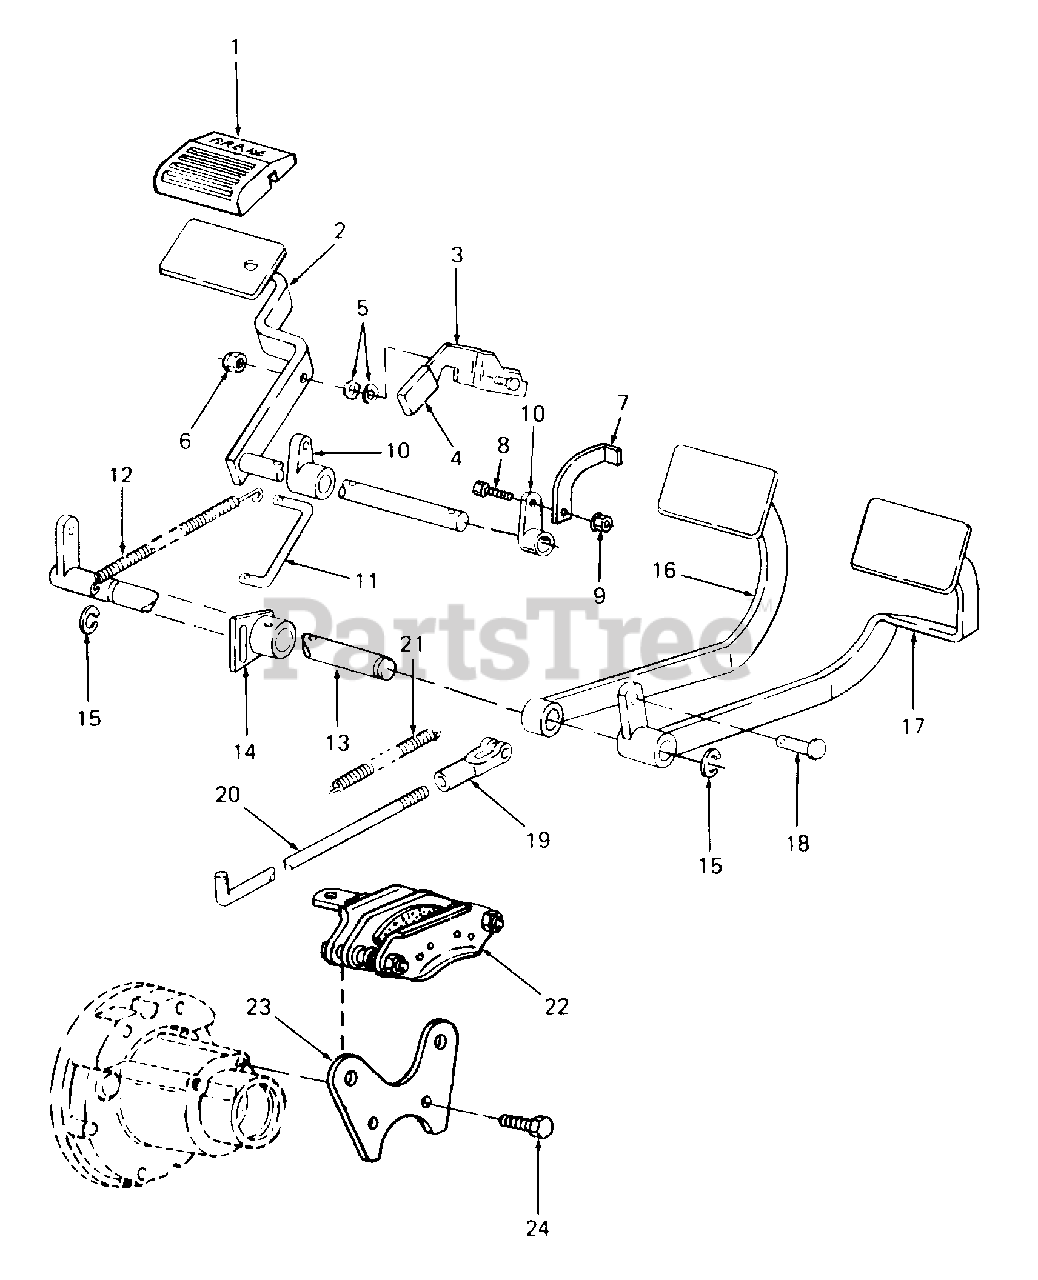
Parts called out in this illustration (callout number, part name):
1	Pad, Brake Pedal
5	Washer, Wave, 1/4 Dia
6	Nut, Hex Insert Lock, 1/4-20
8	Screw, Hex Cap, 3/8-16 X .75 Lg GR5
9	Nut, Hex Flanged Lock, 3/8-16 GR5
11	Rod, Center Brake
12	Spring, Extension, .50 OD x 7.32 LG
13	Shaft Assy, Brake
14	Arm Assy, Parking Brake Plate
15	Ring, Retaining
18	Pin, Clevis, 3/8 Dia x 1.56 LG
19	Clevis, Adjustment
20	Rod, Brake
21	Spring, Extension, .66 OD x 3.3 Lg
22	Kit, Brake Caliper
23	Bracket, Brake Mounting
24	Bolt, Hex Patch, 5/16-18 x 1.0 Lg GR5
